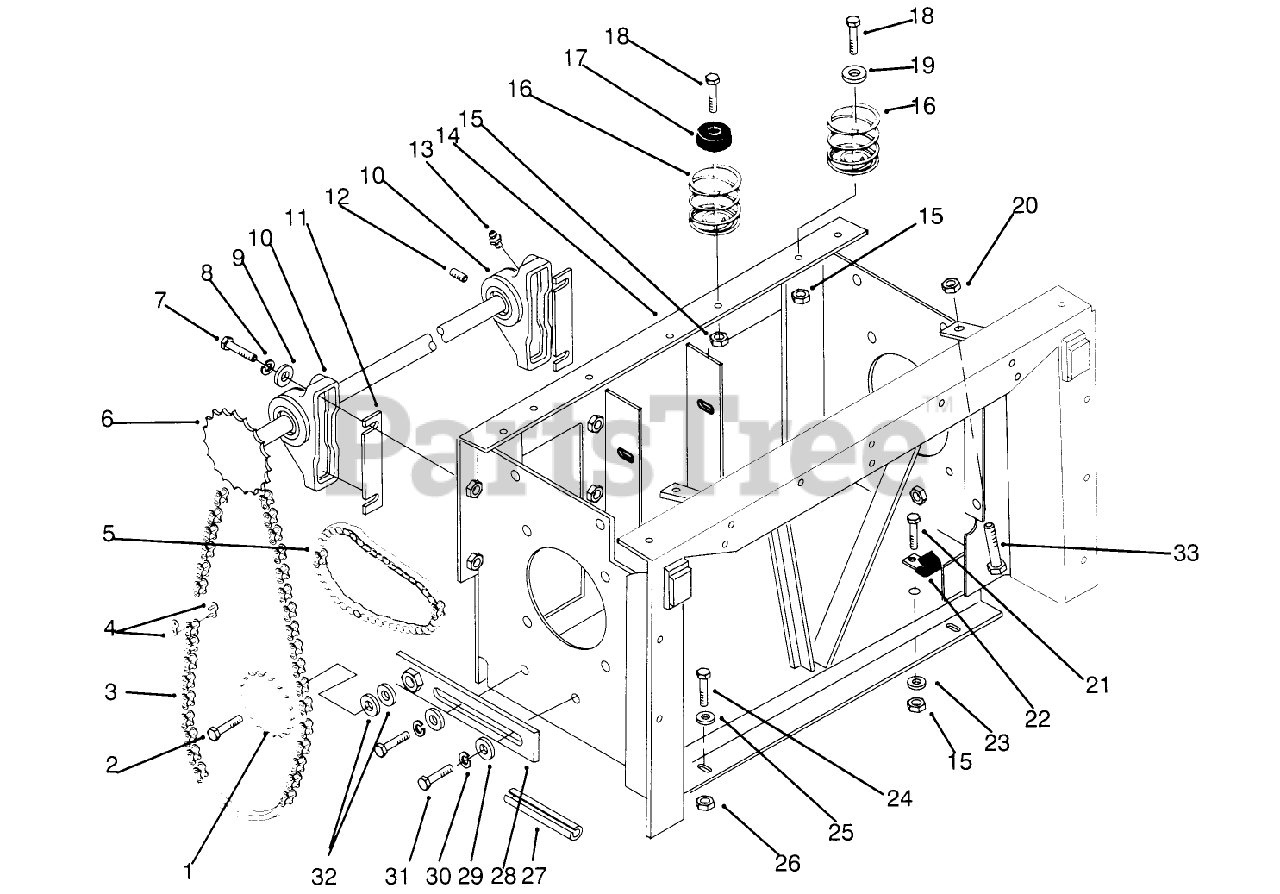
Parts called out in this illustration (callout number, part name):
2	SCREW-HH
6	ASSY-JACKSHAFT *PLT
7	SCREW-HH
8	WASHER-LOCK
9	WASHER-FLAT
11	SHIM-PILLOW BLOCK
12	SCREW-HSH
13	FITTING-GREASE
14	WLDMT-FRAME TRANS *B
15	NUT-LOCK, NI
16	SPRING-SEAT NYLON
17	BUMPER
18	SCREW-HH
19	WASHER
20	NUT-HEX
21	SCREW-HH
22	CLIP
23	WASHER-PLAIN
24	SCREW-HH
25	WASHER-FLAT
26	NUT-LOCK, NI
29	WASHER
30	WASHER-LOCK
31	SCREW-HH
32	WASHER-FLAT
33	SCREW-HH
